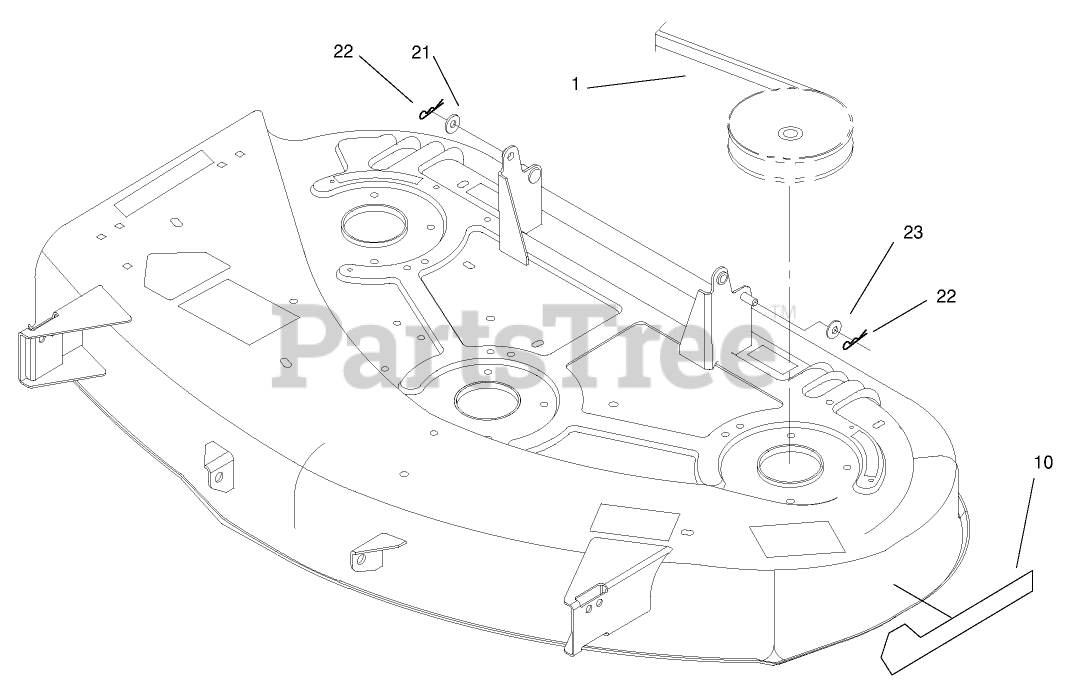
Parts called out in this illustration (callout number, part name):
1	V BELT-DECK
21	WASHER-FLAT
23	WASHER-HARDENED
